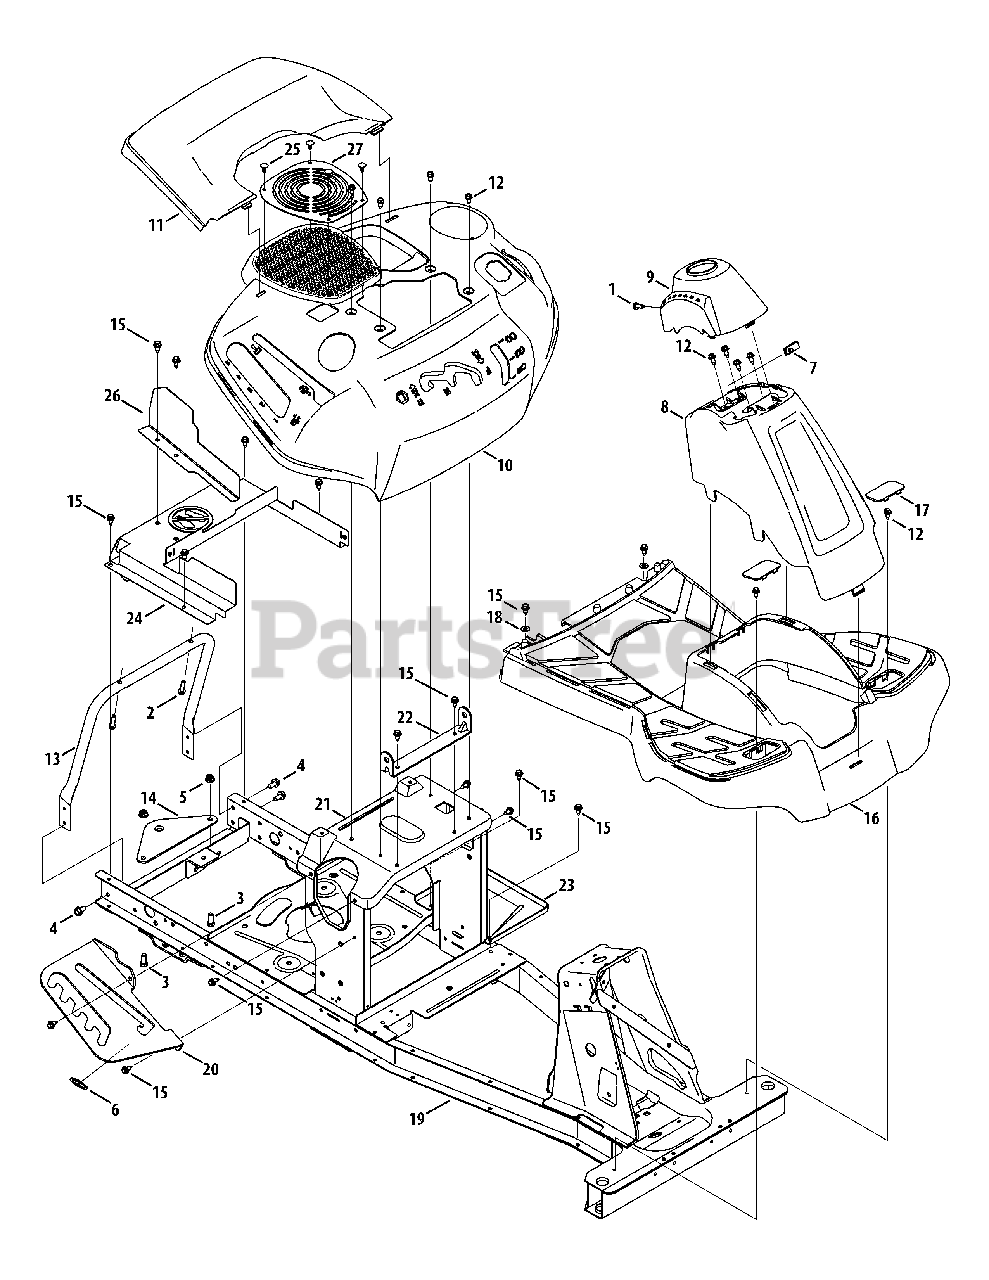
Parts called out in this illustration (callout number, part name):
1	Machine Screw, 1/4-20, 0.750
2	Hex Screw, 1/4-15, 1.000
3	Hex Head Screw, 5/16-18, .75
4	Screw 5/16-18 x .750
5	Flange Locknut, 5/16-18
6	Speed Nut
7	U-type Speed Nut, 1/4-20
8	Column Cover
9	Steering Column Cap
10	Fender, (B&S Eng.)
10	Fender, (MTD Eng. 4P90JUA)
11	Rear Cover
12	Shoulder Screw, .368 X.113 x 1/4-20
13	Rear Cover Support Tube
14	Hitch Plate
15	Tap Screw, 1/4-20, .625
16	Running Board
17	Running Board Plug
18	Flat Washer, .250 x .630 x .052
19	Frame Assembly
20	Deck Lift Index Bracket
21	Seat Pan
22	Seat Pivot Bracket
24	Top Rear Drive Cover
24	Top Rear Drive Cover, (MTD Eng. 4P90JUA)
25	Clip, .250 Dia., (MTD Eng. 4P90JUA)
26	Shield, (MTD Eng. 4P90JUA)
27	Screen Cover, (MTD Eng. 4P90JUA)
